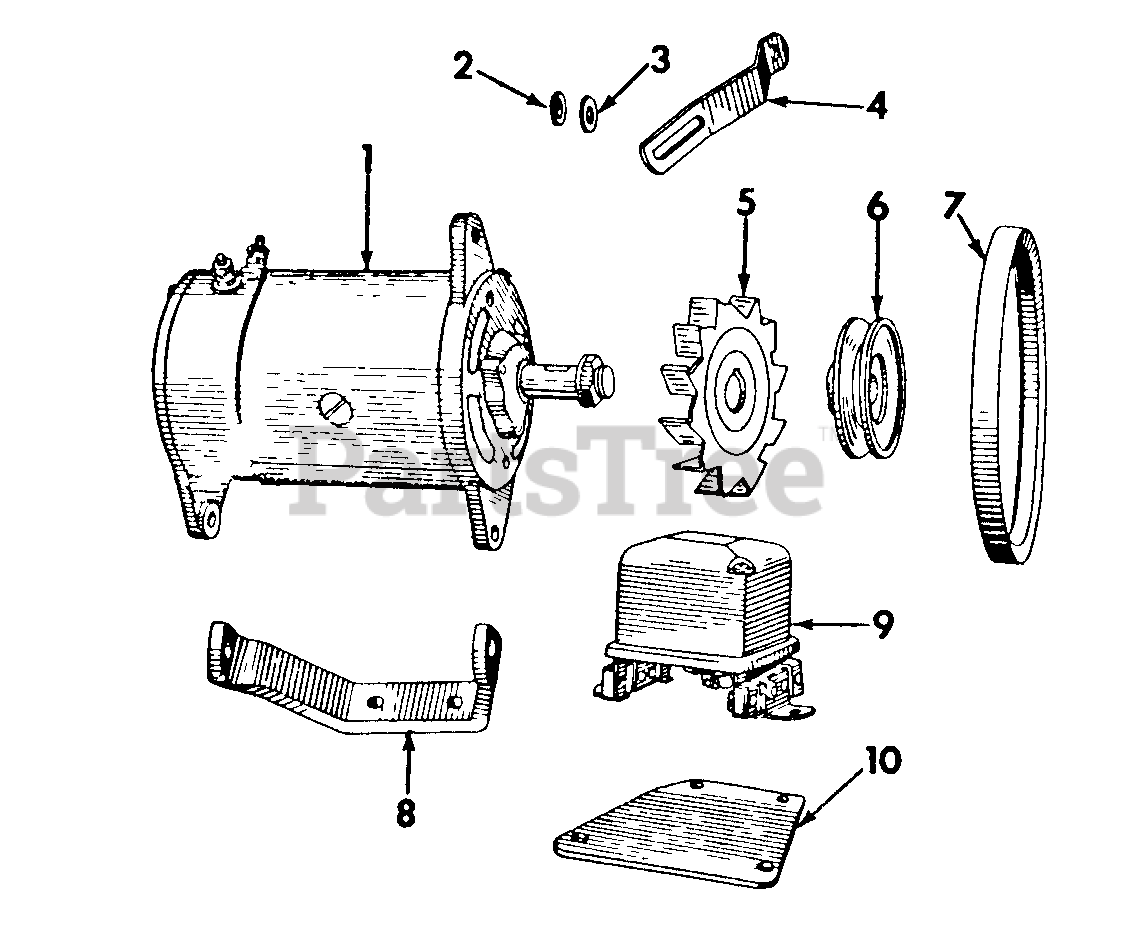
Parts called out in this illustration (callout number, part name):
1	GENERATOR ASSY - 6 VOLT
1	GENERATOR ASSY - 12 VOLT
2	SPACER, GENERATOR BRACE
3	WASHER, 11/32 X 3/4 X .105
4	BRACE, GENERATOR
5	FAN, GENERATOR
6	PULLEY, GENERATOR
7	BELT, GENERATOR
8	BRACKET, GENERATOR
9	REGULATOR ASSY, VOLTAGE - 6 VOLT
9	REGULATOR ASSY, VOLTAGE - 12 VOLT
10	BRACKET, VOLTAGE REGULATOR MOUNTING
